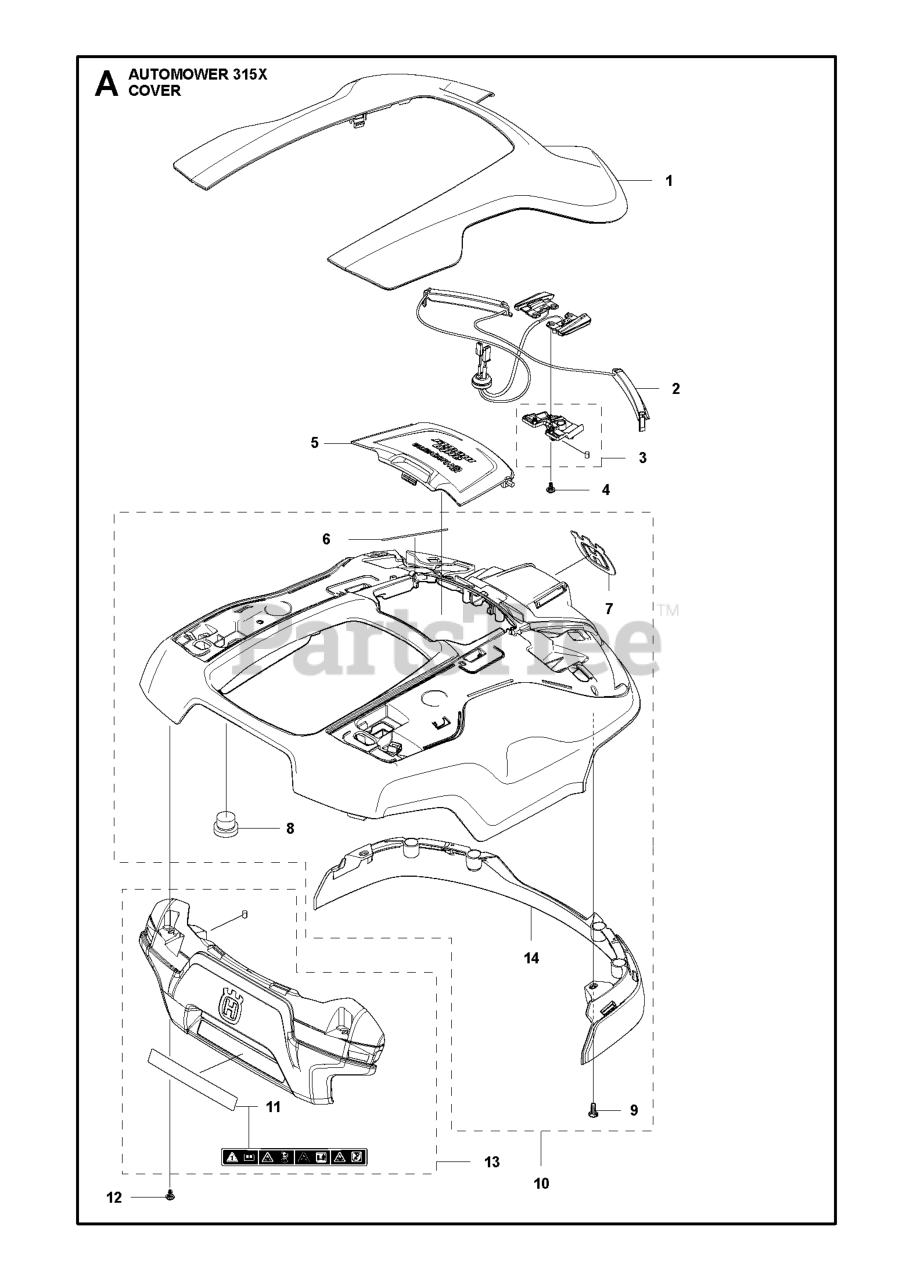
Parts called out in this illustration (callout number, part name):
1	BODY KIT GREY 315X
1	BODY KIT WHITE 315X
2	WIRING ASSY LED LIGHT & CHARGI
3	HOLDER KIT MAGNET
4	SCREW ITXPANT
5	HOOD HEIGHT ADJUSTMENT 315X
6	SPRING D1.8 L100
7	DECAL HUSQVARNA CROWN HEIGHT 5
8	CAP SNAPLOC
9	SCREW ITXPANT
10	BODY KIT
11	LABEL WARNING P15
12	SCREW ITXPANT
13	BUMPER KIT
14	BUMPER FRONT IN RUBBER
